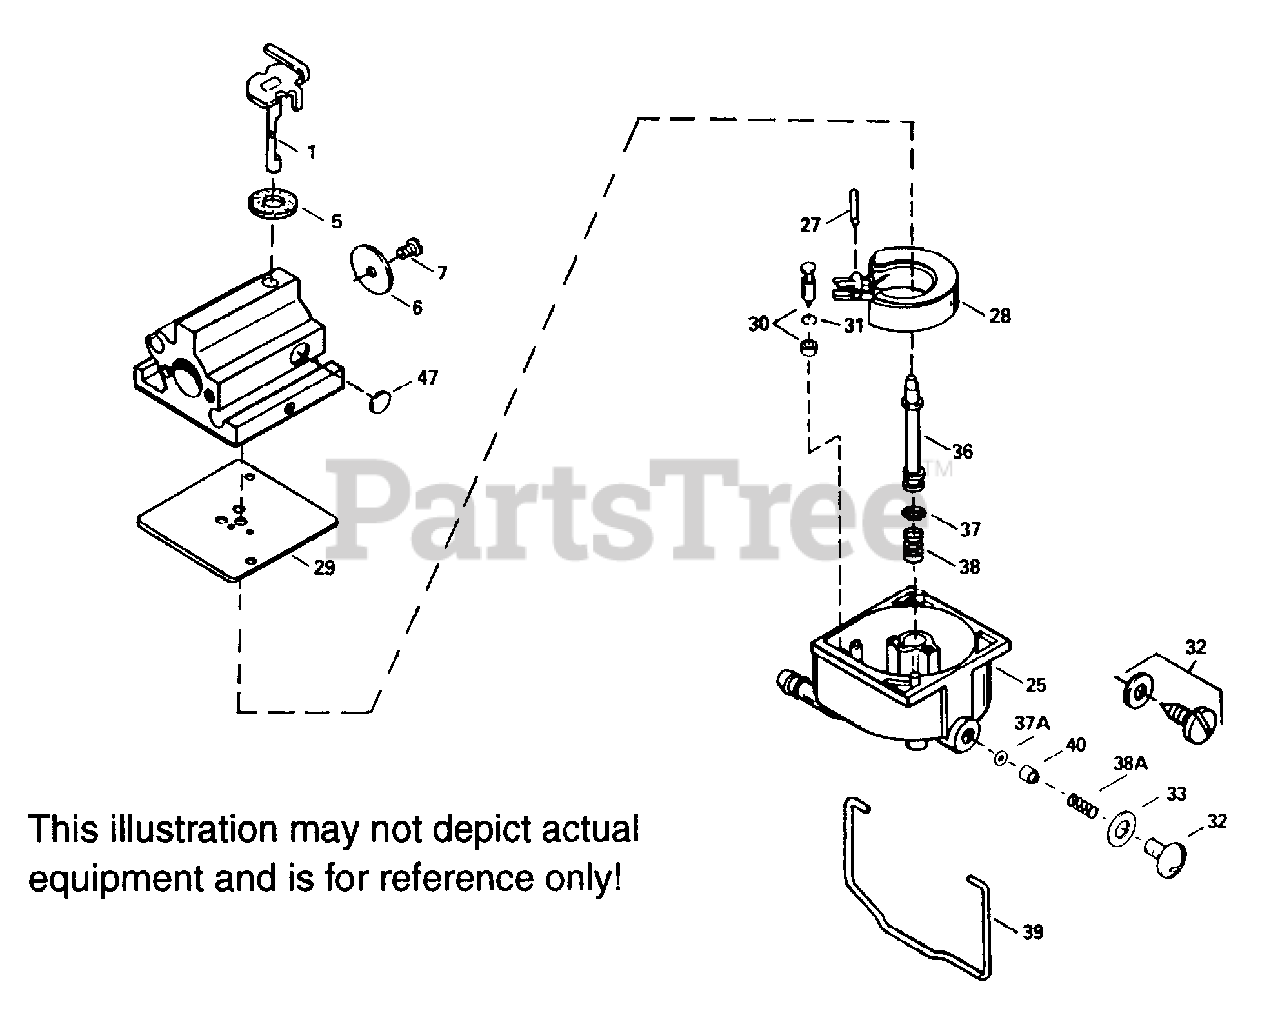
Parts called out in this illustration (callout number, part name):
1	Throttle Shaft & Lever Assembly
5	Dust Seal
6	Throttle Shutter
7	Shutter Screw
14A	Venturi
25	Float Bowl Ass'y.
25A	Float Bowl Assembly Repair Kit
27	Float Shaft
29	Float Bowl to Body Gasket
30	Inlet Needle & Seat
32	Bowl Drain Screw
33	Bowl Drain Washer
36	Main Nozzle Tube
37	"O" Ring
39	Float Bowl Retainer
40	Main Fuel Jet
47	Welch Plug, Idle Mixing Well
